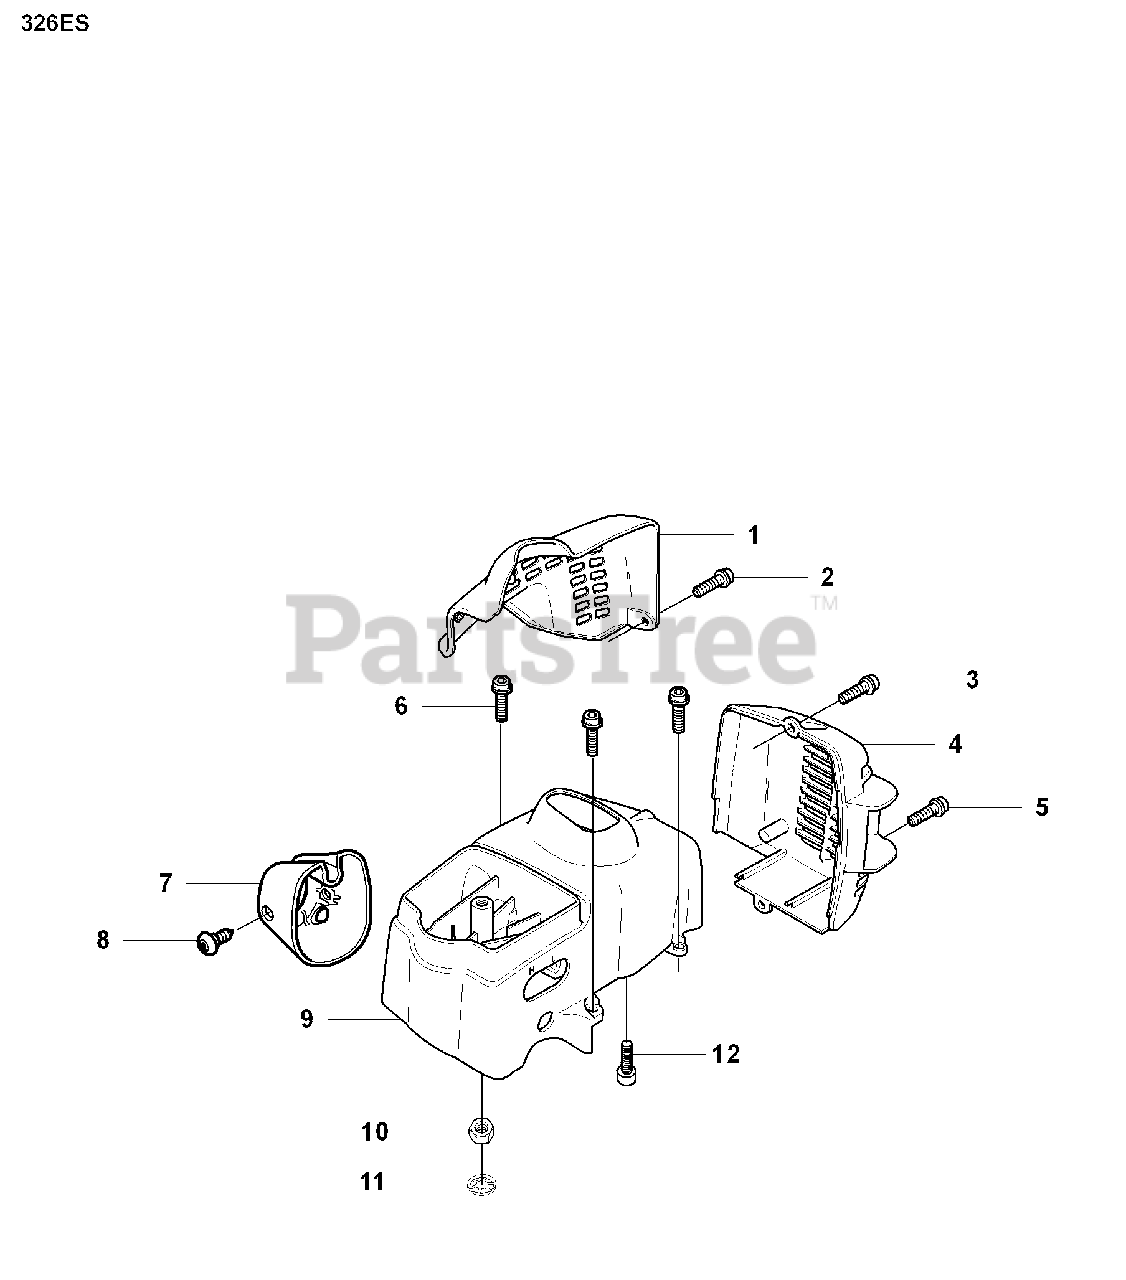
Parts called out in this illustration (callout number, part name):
1	HEAT PROTECTOR, CYLINDER
2	SCREW
3	SCREW
5	SCREW
6	SCREW
8	SCREW MT5X11
9	CYLINDER COVER
12	SCREW
